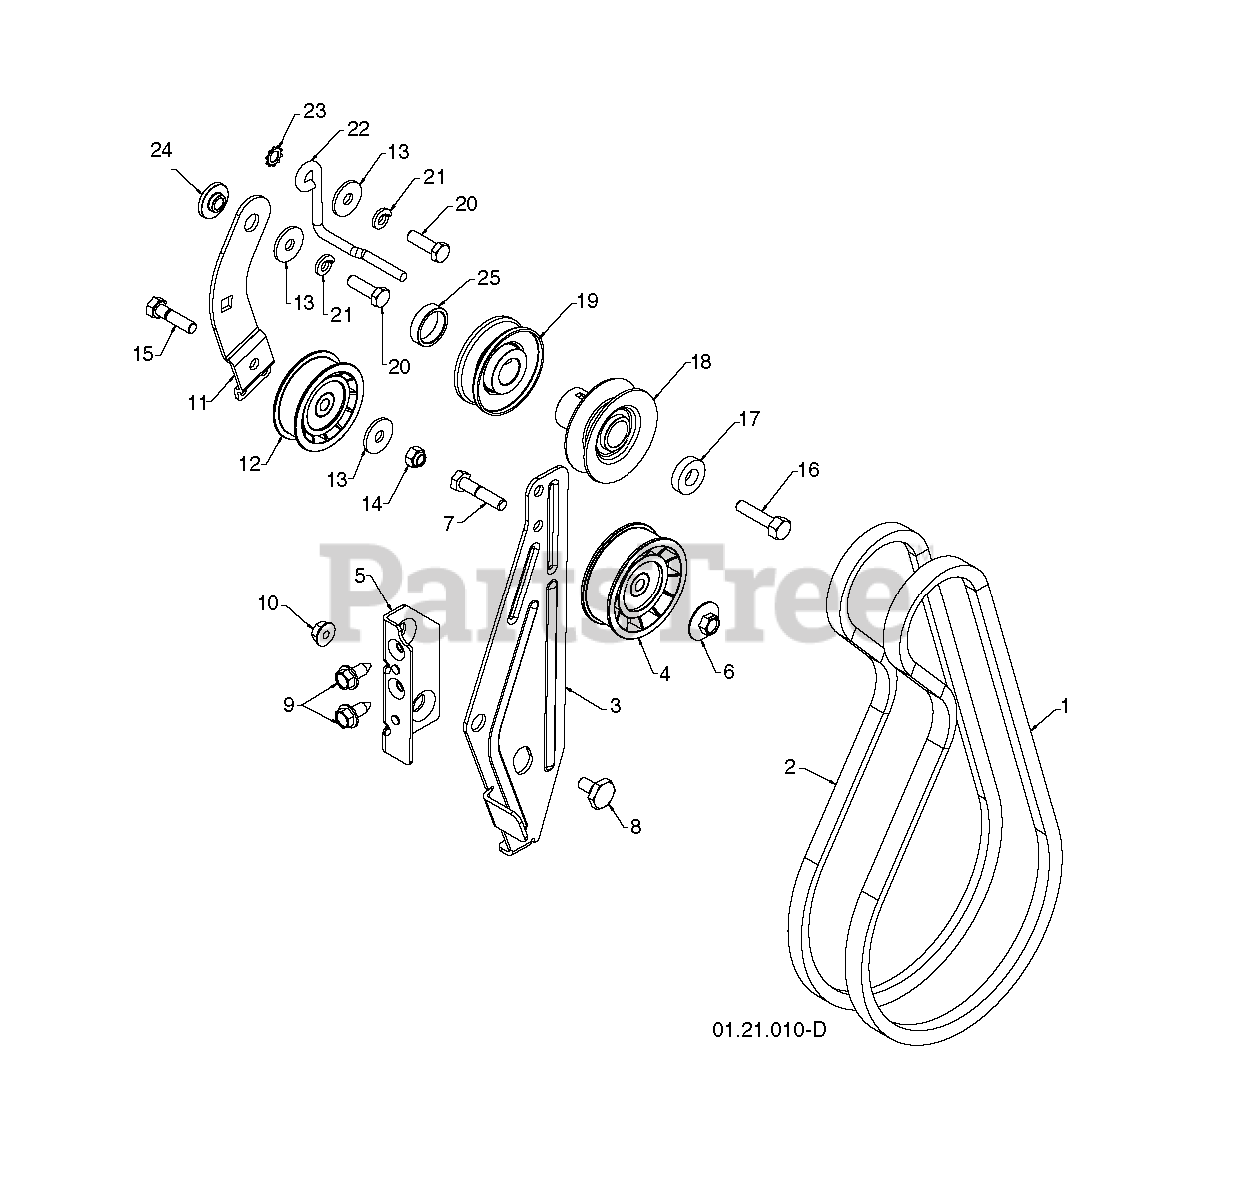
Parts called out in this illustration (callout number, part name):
1	VBELT; IMPELLER_39.09
2	V-BELT.TRACTION.HYDRO
3	ARM.IDLER.BRAKE.
4	PULLEY.IDLER.W/SPACER.
5	RP BRACKET.IDLER.PIVOT
6	NUT.FLANGE.HEX.5/16X18.BLACK
7	HEX BOLT
8	BOLT.SHOULDER.1/2X12
9	BOLT.5/16HEX.WHS.HD
10	NUT.LOCK.5/16-18
11	ARM, IDLER
12	PULLEY.W/SPACER.2.25
13	STEEL WASHER
14	NUT.71038.31-18.HEX.NYLOCK
15	BOLT.5/16-18X1-1/4 FULL.THREAD
16	SCREW, HEX HD 3/8-24 X 1-3/8
17	WASHER, FLAT 3/8
18	PULLEY.ENG.IMPELLER.SNOW
19	PULLEY,ENGINE TRACTION DRIVE
21	WASHER.LOCK.HVY.HLCL.SPR.5/16
22	GUIDE.BELT.HYDRO.H
23	WASHER EXT TOOTH LOCK 5/16
24	RP BUSHING, IDLER PIVOT
25	SPACER.ENGINE.PULLEY
